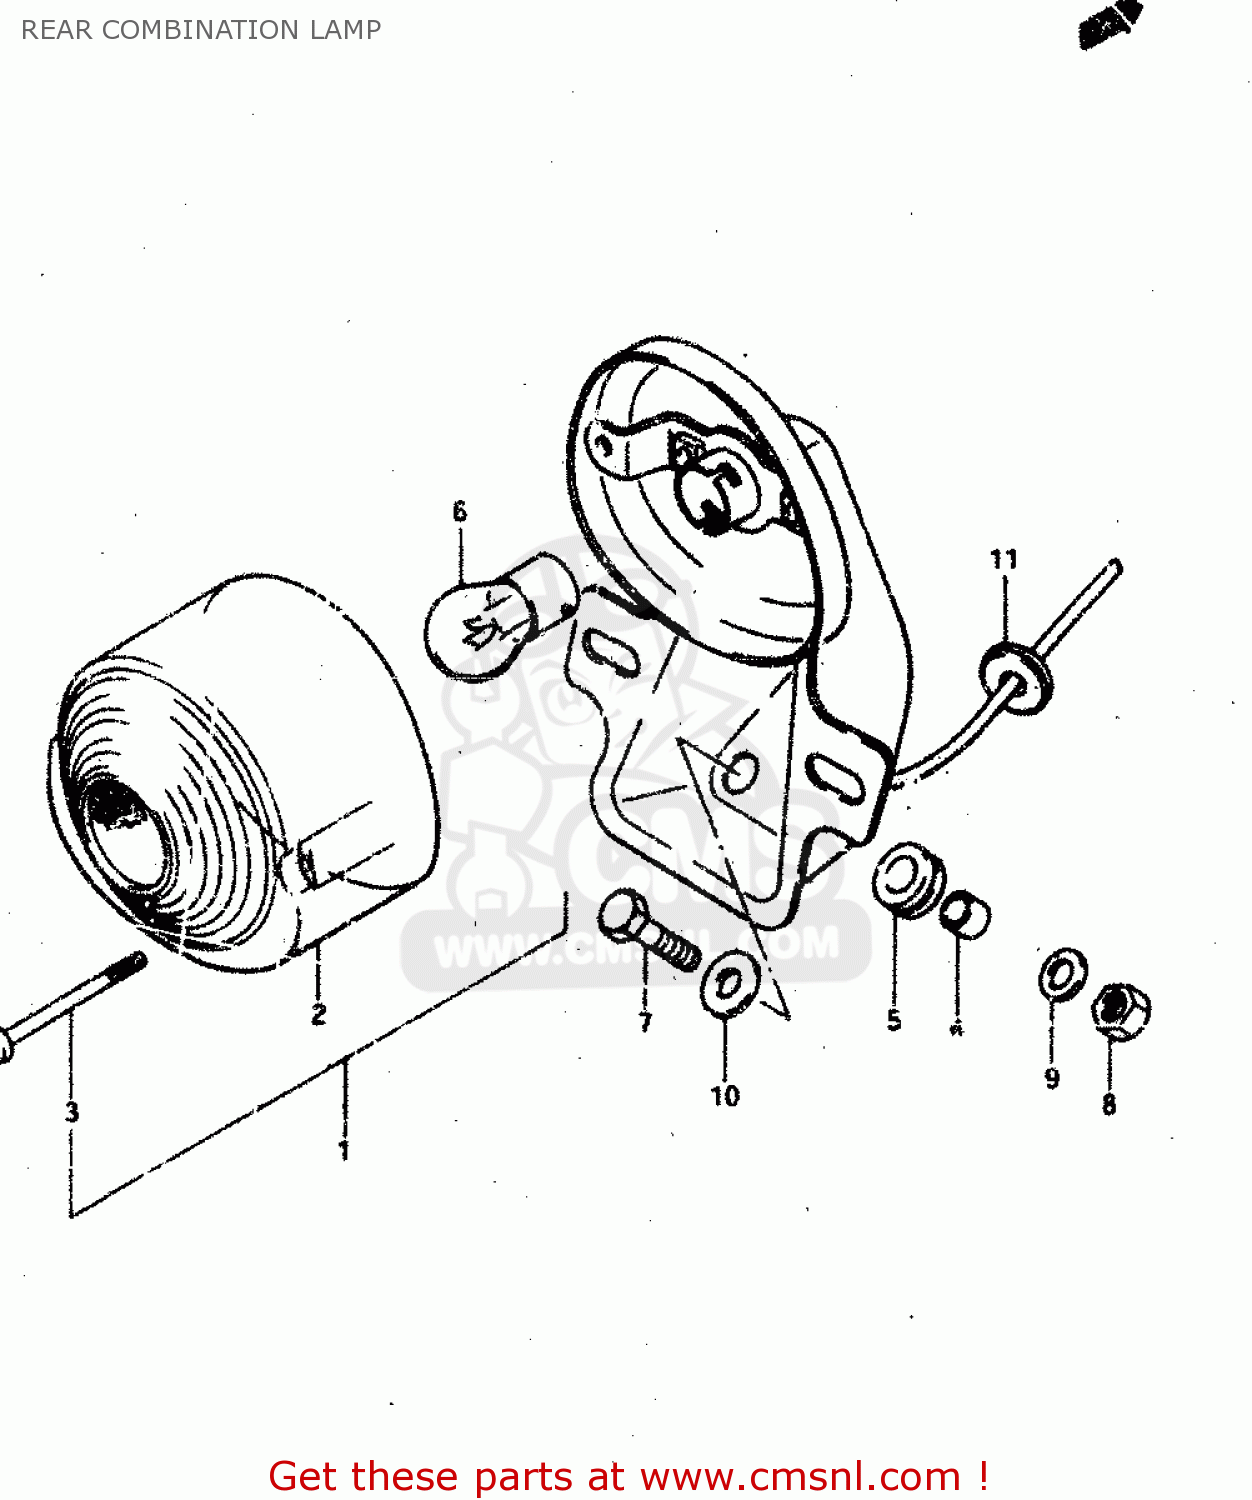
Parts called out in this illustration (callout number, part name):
1	LAMP ASSY,RR COMBINATION
2	LENS,REAR COMBINATION LAMP
3	SCREW
4	SPACER,REAR COMBINATION LAMP
5	CUSHION
6	BULB(6V10/3W,STANLEY,A4854H)
7	BOLT, UPPER
8	NUT
9	WASHER
10	WASHER (6.5X20X1.2)
11	GROMMET
